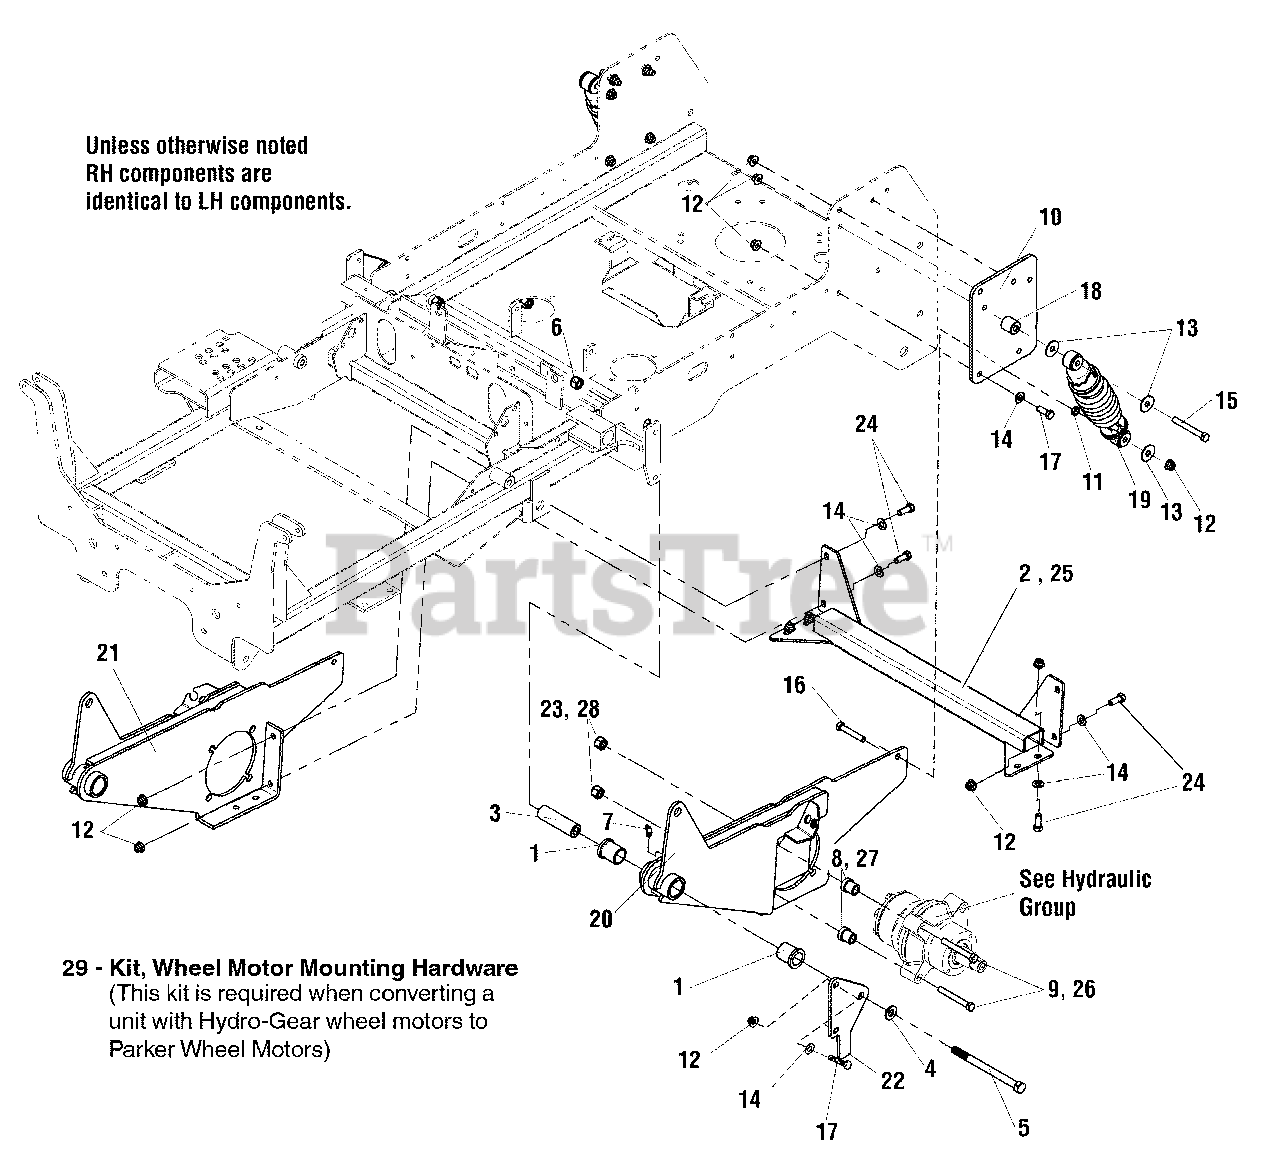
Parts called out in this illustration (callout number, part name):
1	BUSHING, FLANGE
2	KIT, TIE BAR
3	SPACER, .52 X 1.00 X 3.42
4	WASHER, 1/2" SAE
5	BOLT, 1/2-13 X 6-1/2" GD5
6	NUT, 1/2-13 HEX NYLON LOCK
7	GREASE FITTING, 1/4-28 STRAIGHT
8	SPACER, .53 X 1.00 X 1.00
9	BOLT, 1/2-13 X 3-1/2" GD5
10	PLATE, FRAME SUPPORT
11	SPACER, .39 X 1.00 X .50
12	NUT, 3/8-16 HEX NYLOCK FLANGE
13	WASHER, 3/8" FENDER
14	WASHER 3/8" SAE
15	BOLT, 3/8-16 X 3-1/2" GD5 YZ
16	BOLT, 3/8-16 X 2-1/4" GD5 YZ
17	BOLT, 3/8-16 X 1" GD5
18	SPACER, .39 X 1.00 X 1.25, CZ
19	COIL - OVER SHOCK ASSEMBLY
20	WELD, MOTOR MOUNT, LH - ORANGE
21	WELD, MOTOR MOUNT, RH - ORANGE
22	SUPPORT, SWING ARM - BLK
23	NUT, 1/2-13 NEX NYLOCK FLANGE
24	BOLT, 3/8-16 X 1-1/4 GD5
25	KIT, TIE BAR, 61 (5404051A)
26	BOLT, 1/2-13 X 3.5, DRI-LOC PATCH
27	SPACER, .53 X 1.00 X 1.00, W/ FLAT, CZ
28	NUT, 1/2-13 SQUARE
29	KIT, WHEEL MOTOR MOUNTING HARDWARE
